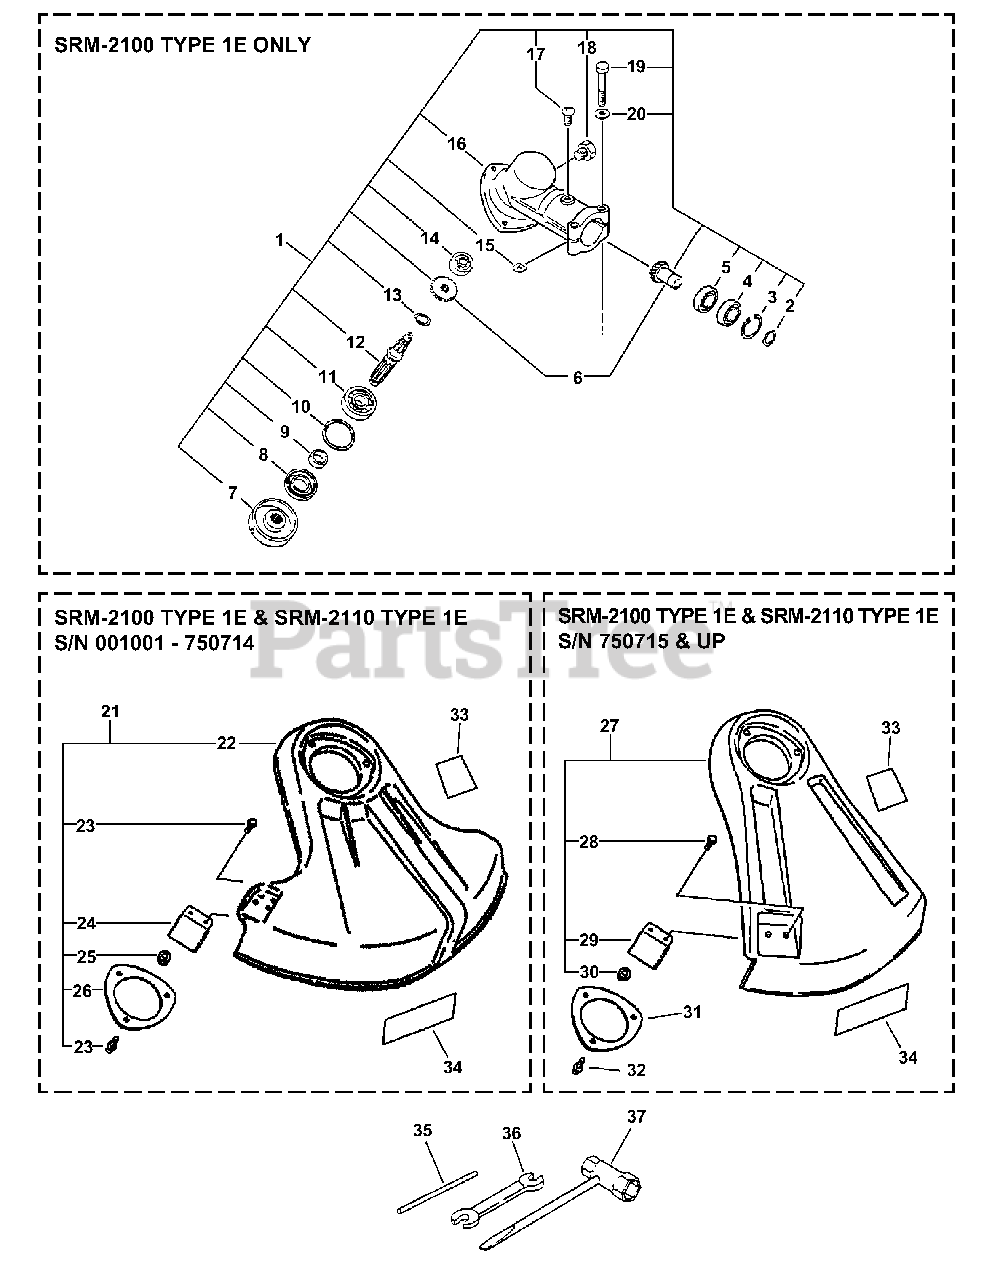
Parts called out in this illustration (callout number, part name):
1	GEAR CASE ASSY
2	RING, SNAP Ø10
3	RING, SNAP Ø22
4	BEARING, BALL 6900Z
5	BEARING, BALL 6900
6	GEAR SET
7	PLATE, ADAPTOR - UPPER
8	SEAL, OIL 22
9	SPACER 11.8×15×9
10	RING, SNAP Ø32
11	BEARING, BALL - 6201 C3
12	SHAFT, GEAR
13	RING, SNAP Ø12
14	BEARING, BALL 609
15	D-WASHER
16	HOUSING, GEAR CASE
17	SCREW 5×10
18	BOLT 8×8 SP
19	BOLT 5×35 SP
20	WASHER, FLAT 5.5×10×0.8
21	DEBRIS SHIELD ASSY
22	SHIELD, DEBRIS
23	SCREW 5×16
24	CUTTER, LINE
25	NUT M5
26	PLATE, SHIELD Ø49.5 MM
27	DEBRIS SHIELD KIT
28	SCREW 5×16
29	CUTTER, LINE
30	NUT M5
31	PLATE, SHIELD Ø49.5 MM
32	SCREW 5×16
33	LABEL, CAUTION
34	LABEL, ECHO
35	TOOL, LOCKING 5×120 MM
36	SPANNER 8×10
37	T-WRENCH 17x-19 L200
